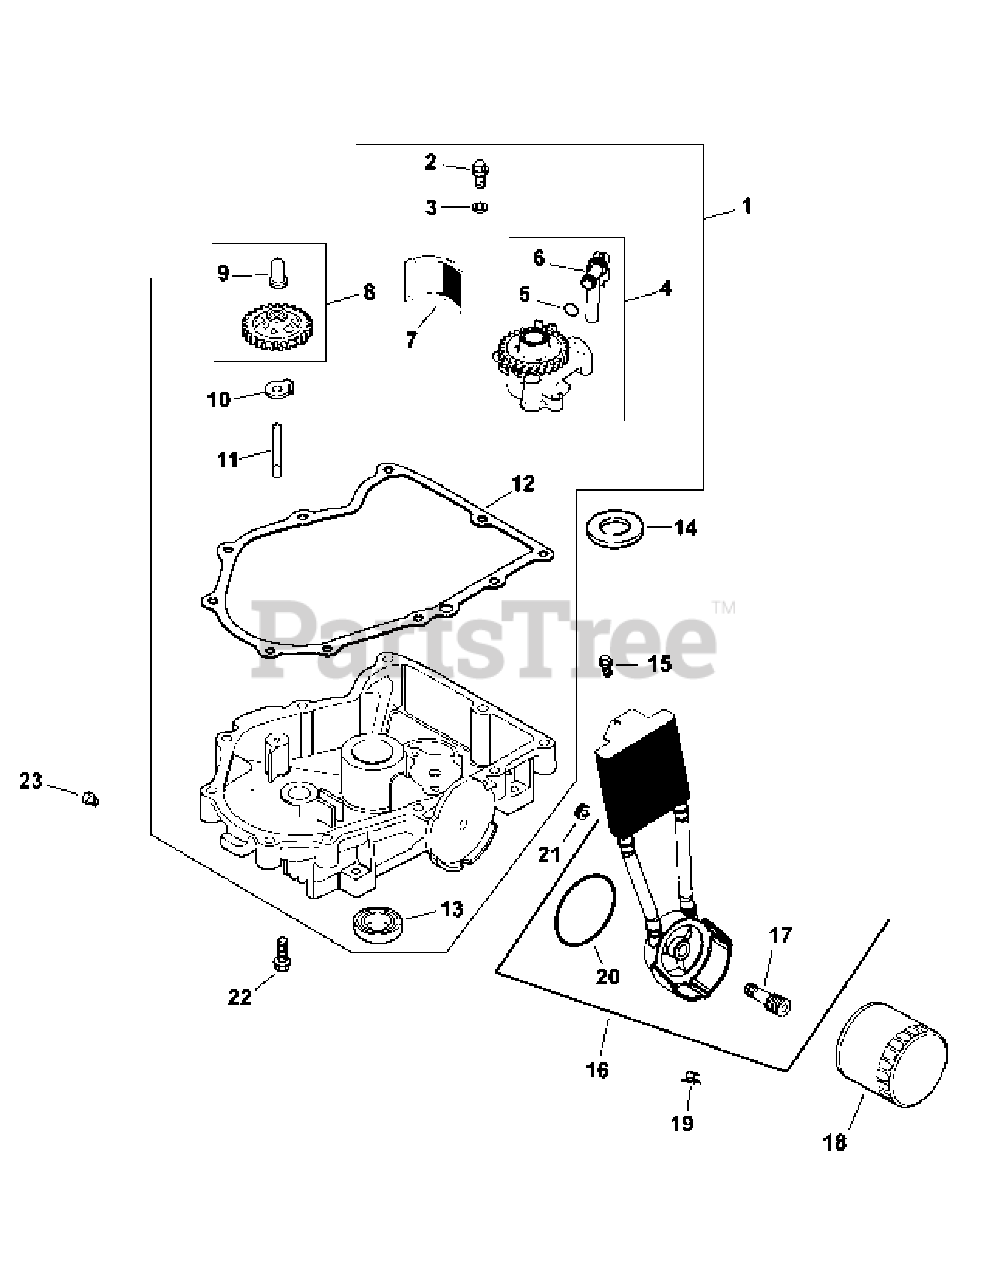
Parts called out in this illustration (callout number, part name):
1	Kit Oil Pan Assembly (Inc. 2-13)
2	Flange Screw, M6 x 1.0 x 25
3	Flat Washer, 6 mm
4	Oil Pump Assembly Kit (Inc. 5 & 6)
5	Oil Pick-Up O-Ring
6	Oil Pick-Up Tube Kit
8	Governor Gear Kit w/Pin (Inc. 9)
9	Governor Regulating Pin
11	Governor Gear Shaft
12	Oil Pan Gasket Kit (Select-A-Seal)
14	Thrust Shim (Black .686 mm)
15	Tap Screw, M6 x 1.7 x 18
16	Oil Cooler Kit (Inc. 17 & 20)
17	Oil Filter Nipple
19	Plastic Nut (Black)
20	Oil Cooler O-Ring
21	Countersink Pipe Plug, 3/8
22	Flange Screw, M8 x 1.25 x 45
23	Pipe Plug, 3/8
